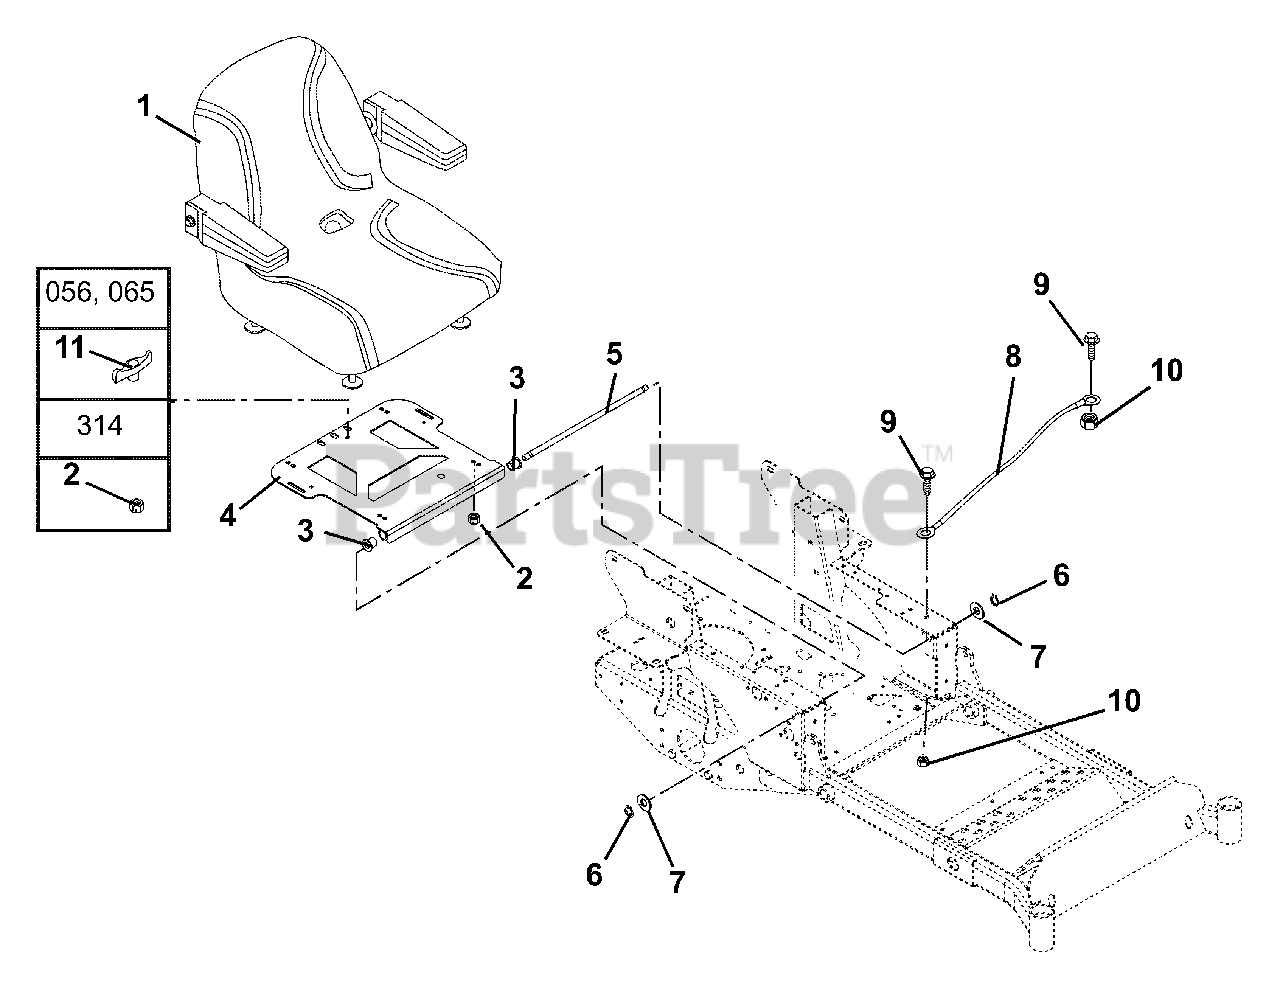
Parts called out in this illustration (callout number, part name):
1	Seat
2	Nut, Locking Top Flange .31-18 (314)
2	Nut, Locking Top Flange .31-18 (056, 065)
3	Bushing, Flange .515 x .750 x .745 x 1.00
4	Seat Pivot Mount
5	Rod, Seat Frame Pivot
6	Ring, Retaining External .50 x .05
7	Washer, Flat Steel .531 x 1.06 x .095
8	Cable, Hood
9	Bolt, Hex .25-20 x .75 Grade 5
10	Nut, Locking Top Flange .25-20
11	Knob, Wing .312-18 (056, 065)
